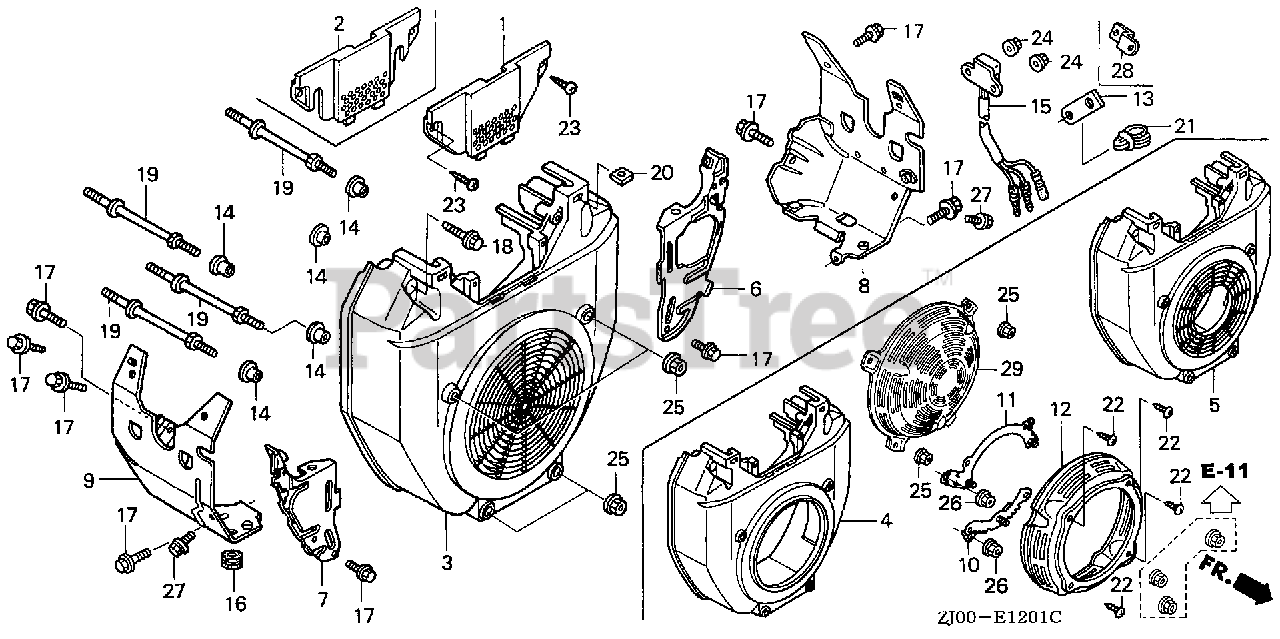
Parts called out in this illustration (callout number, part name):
4	COVER, FAN *R280* (RECOIL STARTER) (POWER RED)
6	PLATE, SIDE (L. SIDE)
7	PLATE, SIDE (R. SIDE)
9	SHROUD (R. SIDE)
14	COLLAR B, TAILLIGHT
16	RUBBER, RR. FENDER CUSHION
17	BOLT, FLANGE (6X12) (CT200)
18	BOLT, FLANGE (6X23) (CT200)
19	BOLT, STUD (6X71)
20	NUT, SQUARE (5MM)
25	NUT, FLANGE (6MM)
27	BOLT, FLANGE (6X8)
